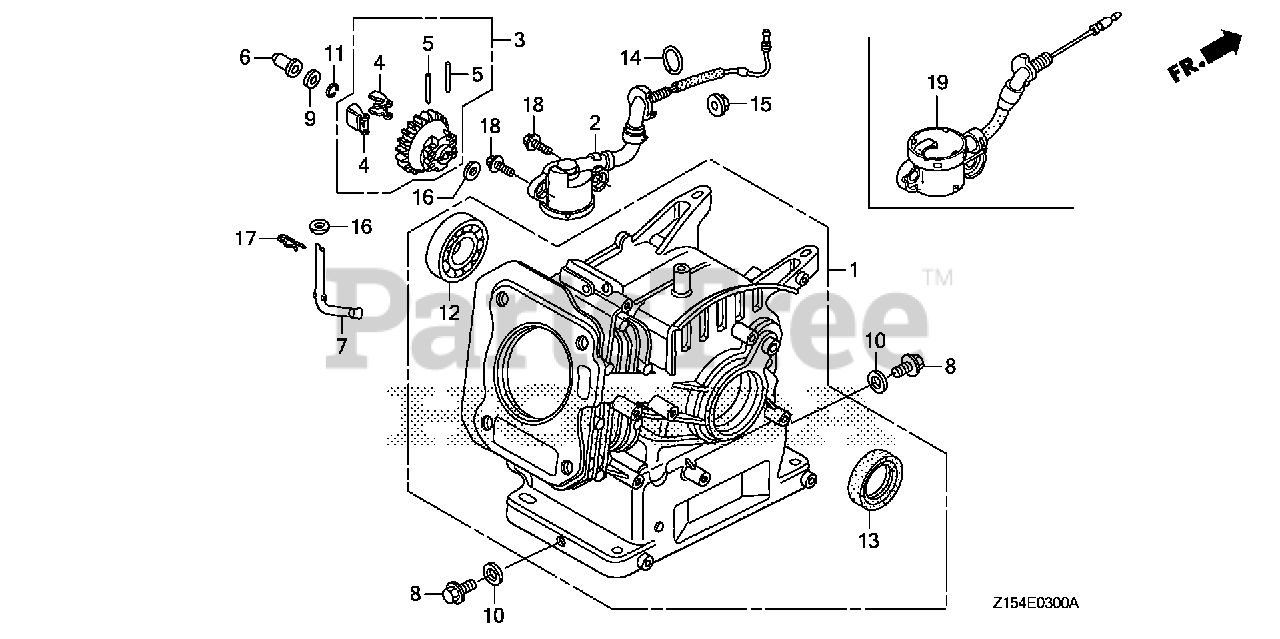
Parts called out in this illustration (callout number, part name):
1	CYLINDER ASSY.
1	CYLINDER ASSY. (OIL ALERT)
2	SWITCH ASSY., OIL LEVEL
3	GOVERNOR ASSY.
4	WEIGHT, GOVERNOR
5	PIN, GOVERNOR WEIGHT
6	SLIDER, GOVERNOR
7	SHAFT, GOVERNOR ARM
8	BOLT, DRAIN PLUG
9	WASHER, THRUST (6MM)
10	WASHER, DRAIN PLUG (10.2MM)
11	CLIP, GOVERNOR HOLDER
12	BEARING, RADIAL BALL (6205TMB) (NTN)
12	BEARING, RADIAL BALL (6205) (NSK)
13	OIL SEAL (25X41X6)
14	O-RING (13.5X1.5) (ARAI)
14	O-RING (14MM) (NOK)
15	NUT, FLANGE (10MM)
16	WASHER, PLAIN (6MM)
17	PIN, LOCK (8MM)
18	BOLT, FLANGE (6X12)
